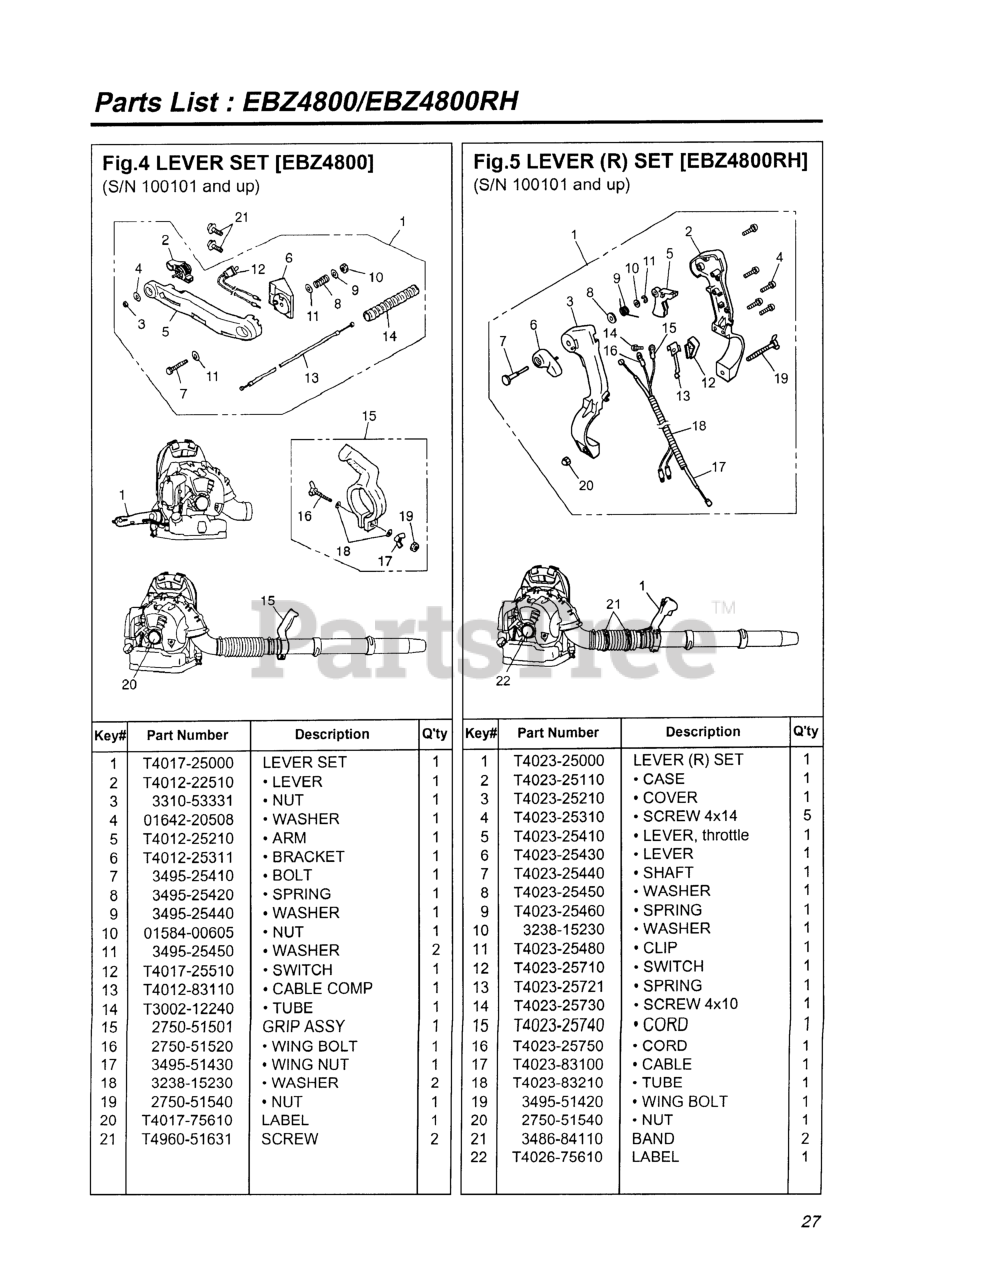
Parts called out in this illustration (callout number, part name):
1	LEVER SET
3	NUT (B)
4	WASHER, M5x.8(RPLS 01624-20508
5	ARM (USE T4012-25211)
6	BRACKET (RPLS -25310)
7	BOLT
8	SPRING
9	WASHER
10	NUT, M6 X 5
11	WASHER, FLAT
12	SWITCH
13	CABLE COMPLETE
14	TUBE (RPLS 4900-72141)
15	GRIP ASSEMBLY (RPLS -51500)
16	WING BOLT
17	NUT, WING
18	WASHER
19	NUT
20	LABEL, RECOIL (EBZ4800)
21	SCREW TORX
